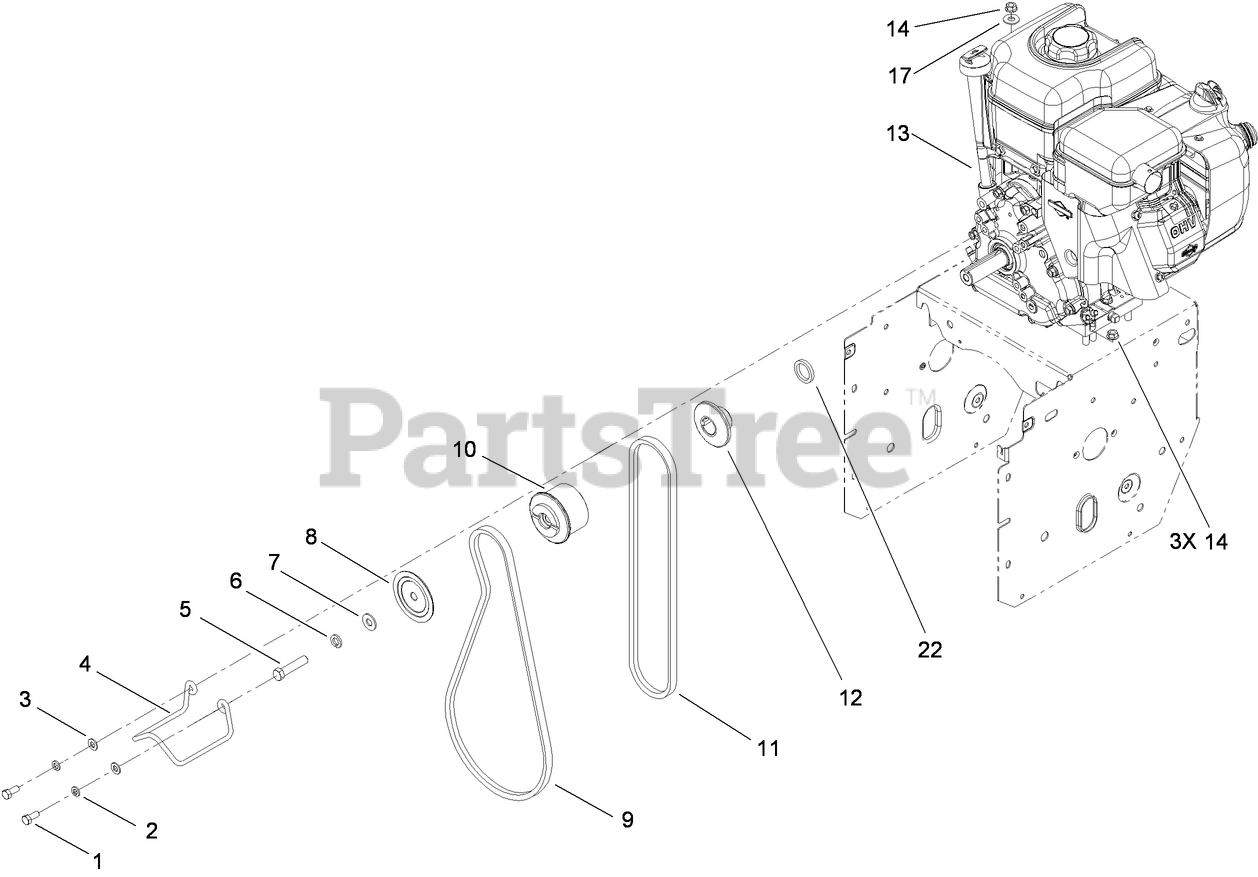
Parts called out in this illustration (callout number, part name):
1	SCREW-HH
2	WASHER-LOCK
3	WASHER-PLAIN
5	SCREW-HH
6	WASHER-LOCK
7	WASHER-FLAT
8	SHEAVE-HALF, IMPELLER
9	BELT-V
10	PULLEY-ENGINE, CENTER
11	V BELT-TRACTION
12	SHEAVE-HALF, TRACTION
14	NUT-HF
17	WASHER-FLAT
22	SPACER-HARDENED
